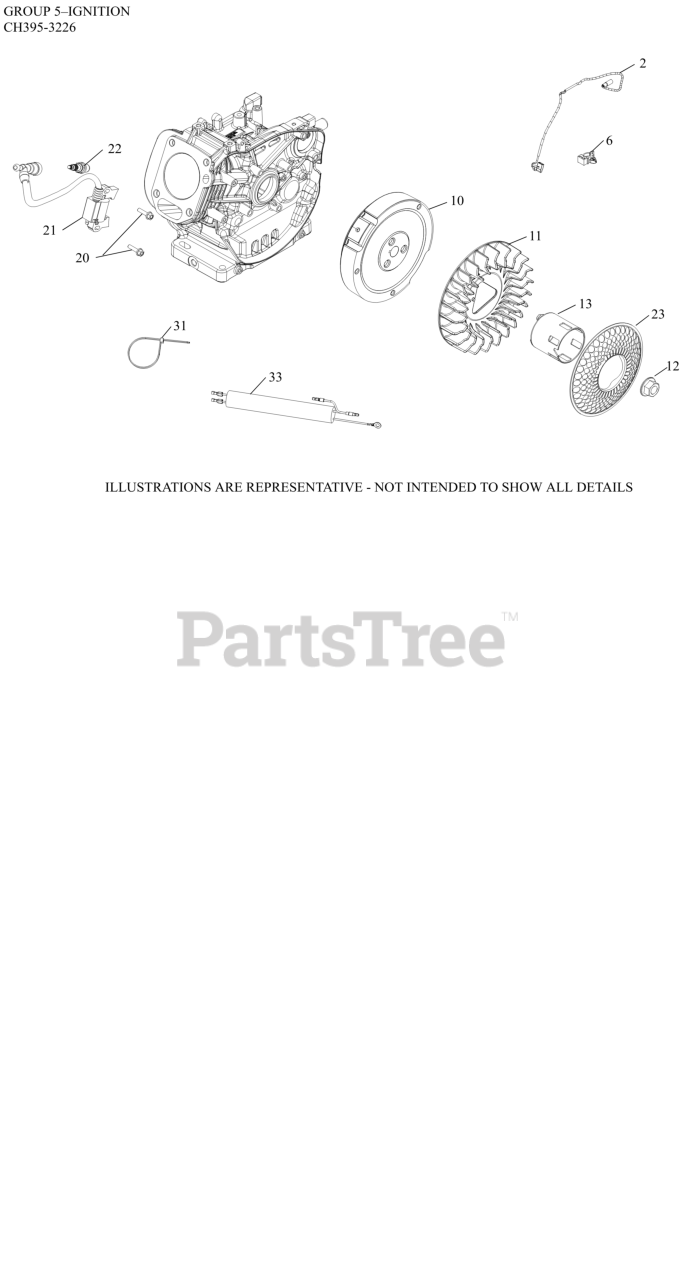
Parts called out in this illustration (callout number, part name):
2	LEAD, GROUND TO KILL
6	CLIP, WIRE HARNESS
10	FLYWHEEL ASSY,CAST IRON (RECOIL)
11	FAN, FLYWHEEL
12	NUT, FLYWHEEL
13	CUP, STARTER DRIVE
20	SCREW, M6 X 25-(#25086436S)
21	MODULE, SPARK PLUG ASSY
22	SPARK PLUG
33	LEAD, MICROSWITCH
